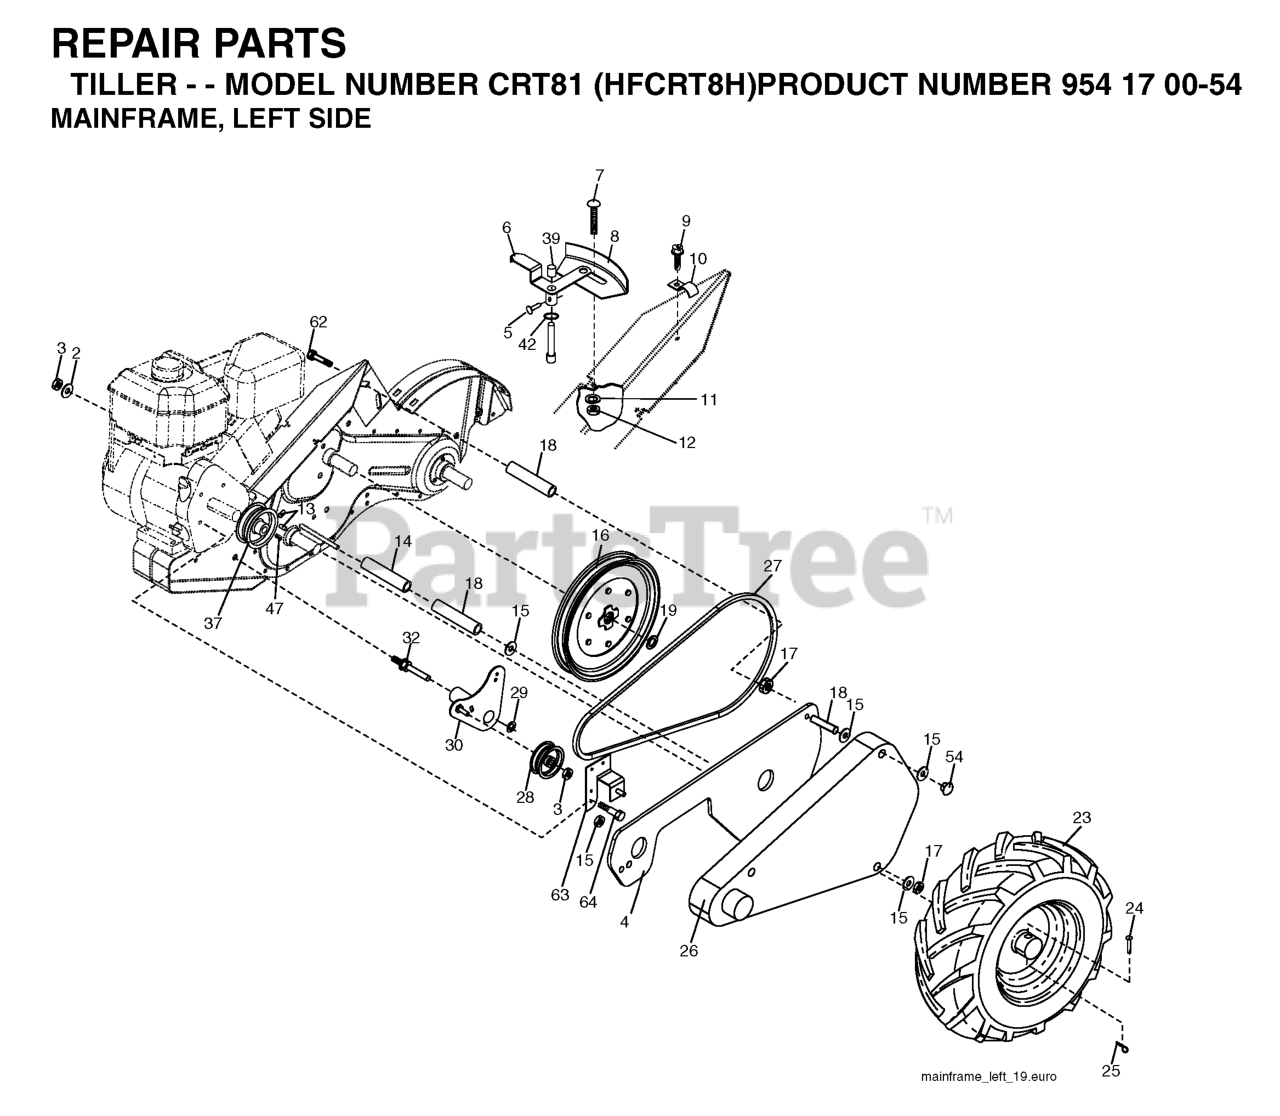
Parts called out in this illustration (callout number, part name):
2	WASHER, LOCK 3/8
3	NUT.HEX.3/8-16UNC
4	Shield, Inner Belt Guard RT
5	PIN.SPIROL.FLARED
6	LEVER ASM CRT
8	PANEL.INDICATOR.SHIFT.BLACK
9	TAPPING SCREW
10	CONDUIT.CLIP.PLATED
11	LOCKWASHER
12	NUT
14	SPACER-SPLIT.327 X .42
15	WASHER
16	SHEAVE, TRANSMISSION
17	NUT
18	SPACER SPLIT
19	RETAINING RING LT
23	TIRE.16X4-8.CHEVRON.TILLER
25	SPRING TI
26	FOOTREST.PNT.LH
27	BELT, DRIVE
28	PULLEY-IDLER TI
30	BRACKET.ASM.IDLER.BLACK
32	SHAFT, IDLER ARM
37	SHEAVE, ENGINE
39	CAP.PLUNGER.BLACK
47	KEY, SQUARE
62	BOLT 5/16-18X4 1/2
63	Bracket Asm Guard
